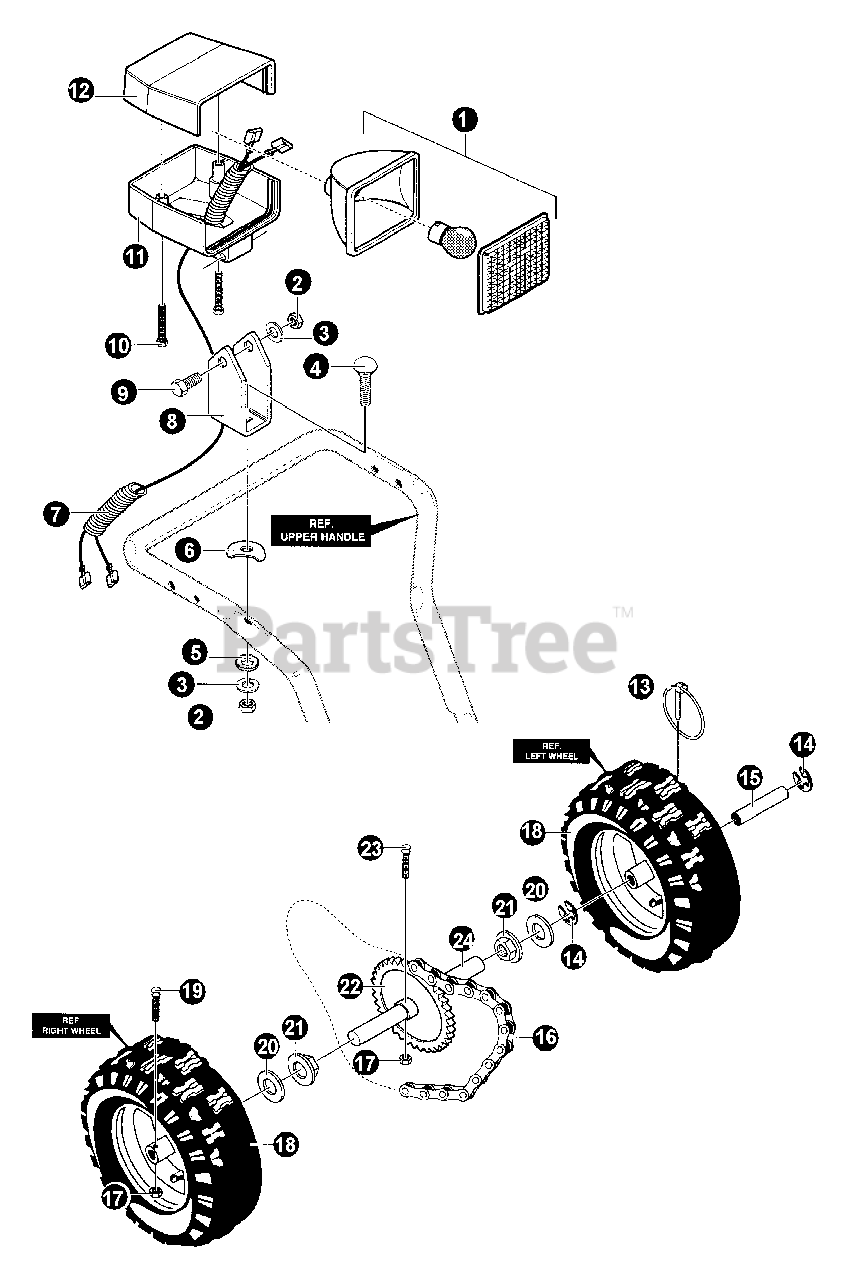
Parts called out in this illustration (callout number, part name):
1	HOUSING, HEAD LIGHT
3	WASHER
4	BOLT, 5/16-18×2.25
5	WASHER
6	WASHER, SADDLE - 5/16"
7	WIRING, HARNESS ASSY
8	BRACKET, HEADLIGHT
9	SCREW, 5/16-18×2.00 HHCFT
10	SCREW - 8×1.75"
11	CASE, HEADLIGHT - LOWER
12	HOUSING, HEADLIGHT UPPER
13	PIN, KLIK
14	RING, RETAINING
15	BUSHING, WHEEL 4" LG
16	CHAIN, ROLLER 420×41
17	NUT, 1/4"-20
18	WHEEL ASSY
19	SCREW - 1/4-20×1.75"
20	WASHER, FLAT
21	BEARING, FL
22	SPROCKET, HUB #40-37TX0.75ID
23	SCREW 1/4"-20×2.25
24	SHAFT, AXLE 6.15
